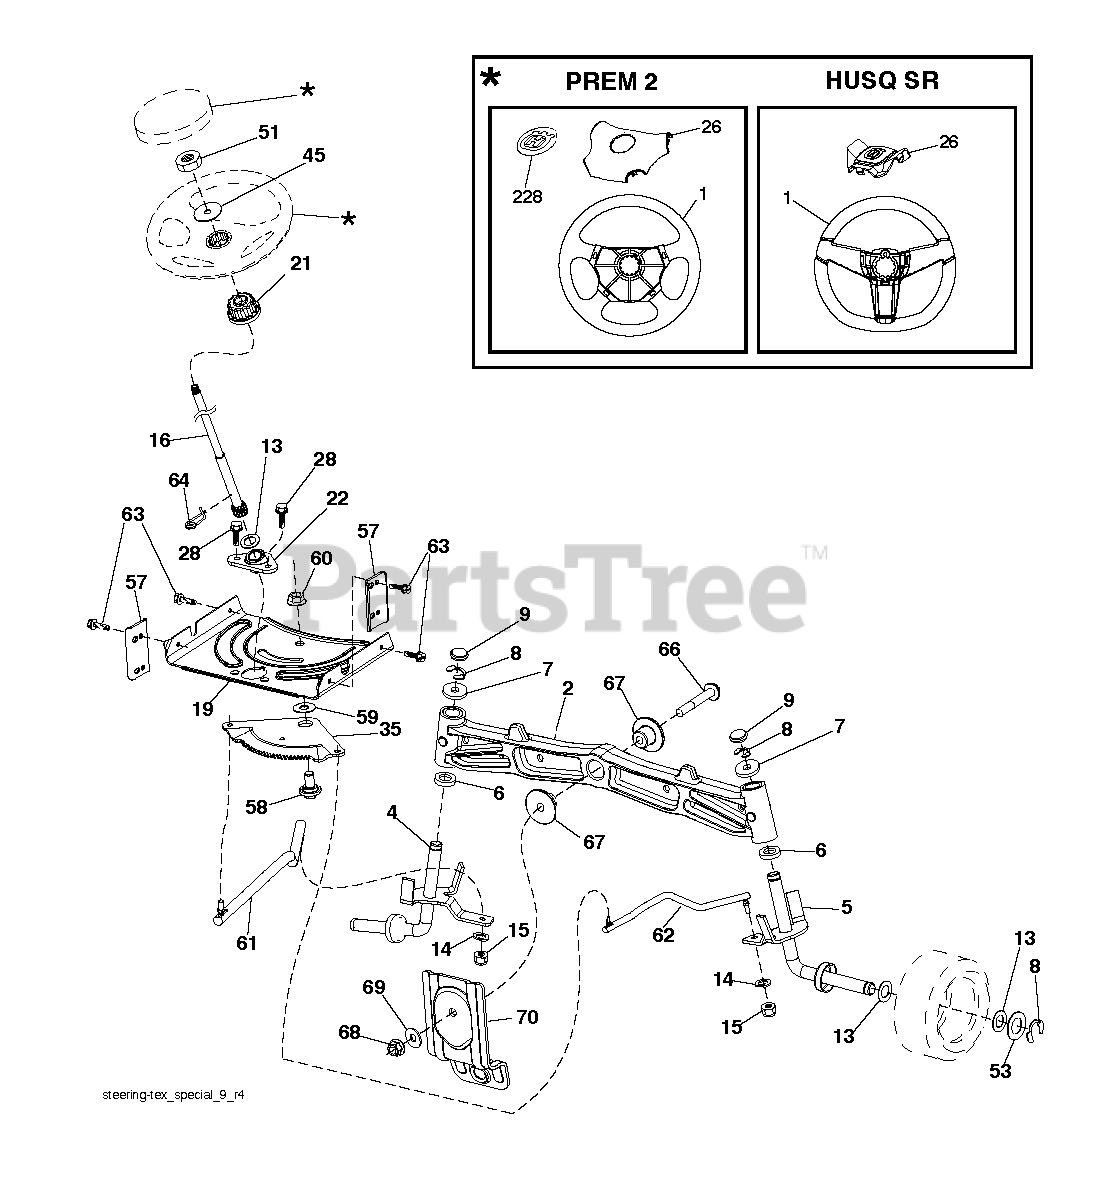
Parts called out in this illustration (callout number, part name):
1	RP WHEEL.STEER.HUSQ.PREM.OVMLD
2	AXLE.CAST.IRON
4	SPINDLE.WELDED.LH.15"TEX
5	SPINDLE.WELDED.RH.15"T
6	THRUST WASHER
9	CAP.SPINDLE.BLACK
14	WASHER, LOCK 3/8
15	NUT CROWNLOCK 3/8-24
16	SHAFT.STEER.STEALTH.DD
19	PLATE.STEER.DDL.NLT/NG
21	ADAPTER, WHEEL STNG..
22	BUSHING.ASM.STEERING.A
26	RP INSERT.CAP.WHL.STRG.HUSQ.
28	SCREW, 3/8-16X3/4
35	GEAR.SECTOR.PLATE.DDL.
45	WASHER 9/16"ID, 2 3/8"OD
51	NUT.HEX.1/2-20
53	WASHER.HARDENED
57	BRACKET.UPSTOP.TEX
58	BOLT.SHOULDER.SECTOR.P
59	WASHER.THURST.SECTOR.S
60	NUT FLANGE LOCK 5/8-11
61	DRAGLINK.LH.BALLSTUD.D
62	DRAGLINK.RH.BALLSTUD.D
63	SCREW
64	RETAINER.CLIP.SPRING.S
66	BOLT HEX FGHD 7/16-14 X 3 SERR
67	BUSHING.PM.FRONT AXLE
68	NUT.LOCK.FLANGE.7/16
69	WASHER.1.5X.505X.118
70	BRKT.DECK.SUSPENSION.F
228	DECAL.WHEEL.STRG.LGN.H
